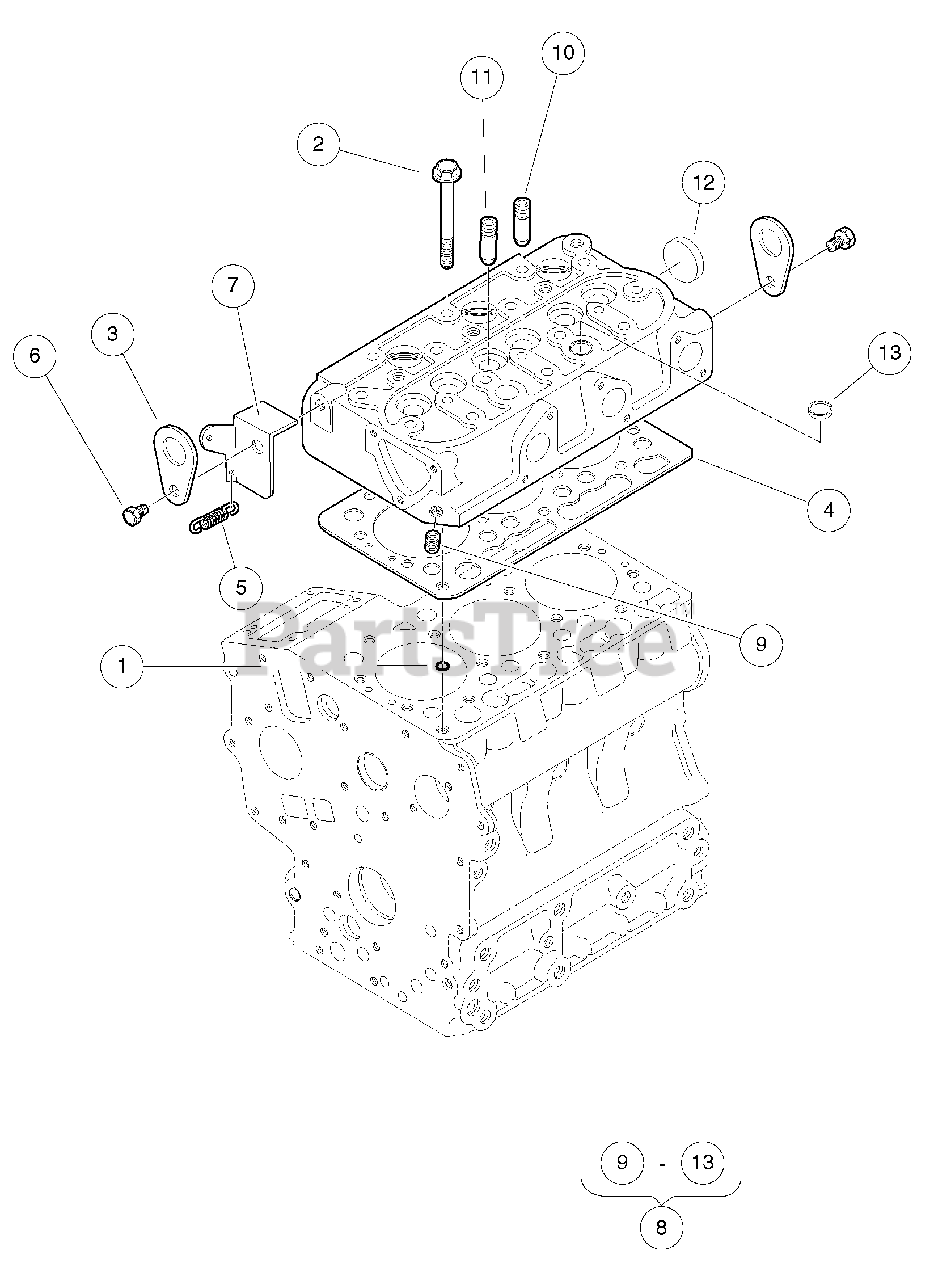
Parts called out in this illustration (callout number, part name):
1	O Ring, 8 X 7
2	Bolt, Cylinder Head
3	Hook, Engine
4	Gasket, Cylinder Head
5	Spring, Start
6	Bolt, Engine Hook
7	Stay, Cylinder Head
8	Head, Cylinder, Complete
9	Plug, 3/32"
10	Guide, Exhaust Valve
11	Guide, Inlet Valve
12	Cap, Sealing, Head
13	Cap, Sealing, Head, Top
